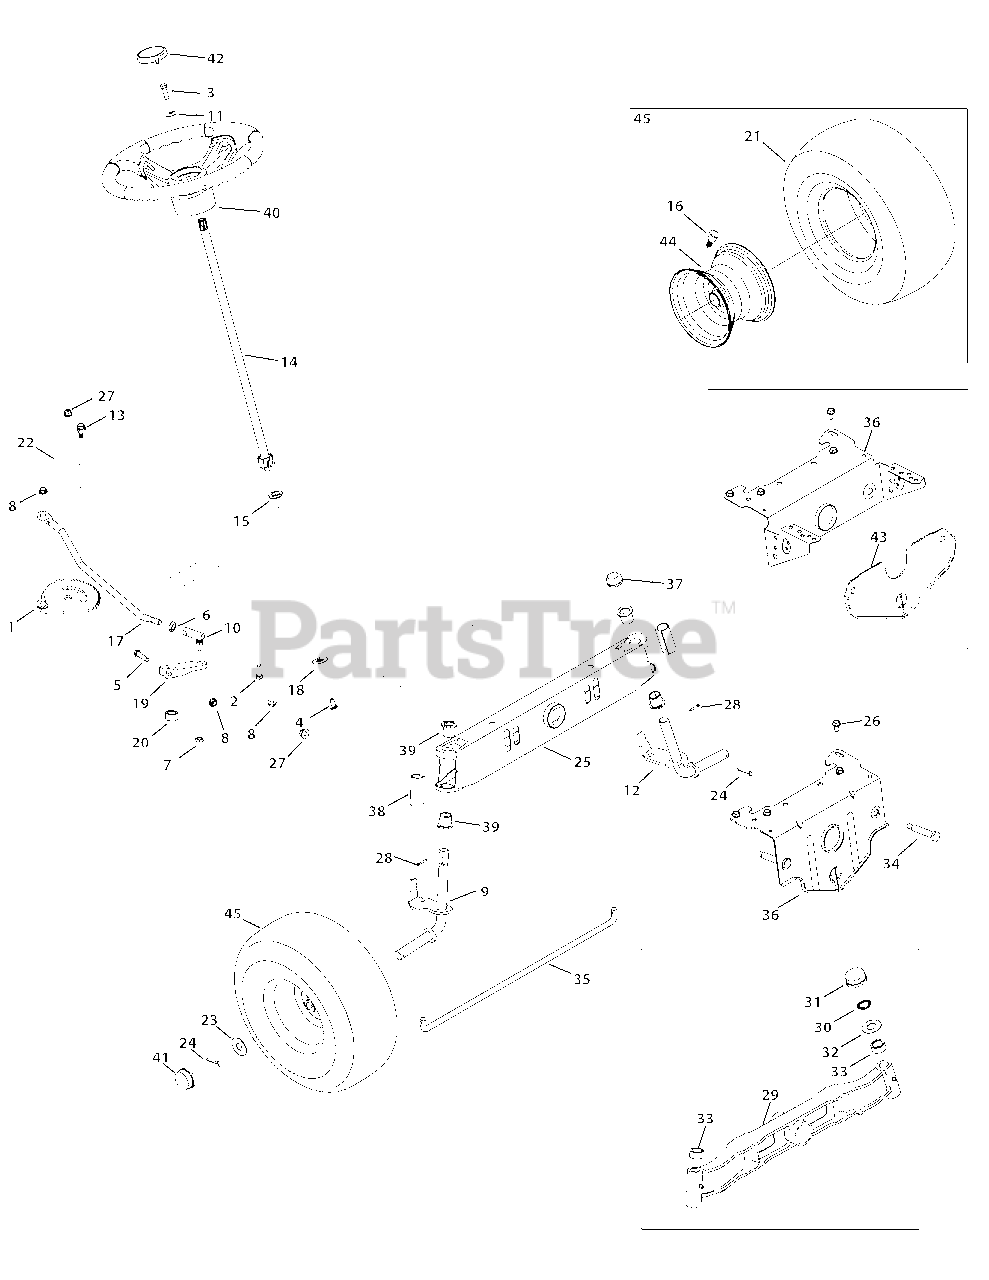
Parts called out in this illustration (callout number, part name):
1	Front Steering Gear Assembly
2	Hex Screw, 3/8-16 x 1.00
3	Hex Screw, 5/16-18 x 1.00, Lock
4	Machine Screw, 5/16-18 x .750
5	Hex Screw, 5/16-18 x 1.75
6	Jam Nut, 7/16-20
7	Jamlock Nut, 3/8-24
8	Flangelock Nut, 5/16-18
9	Axle, 42" & 46" Front RH
10	Ball Joint, 7/16-20
11	Bell Washerer, .340 x .872 x .060
12	Axle, 42" & 46" Front LH
13	Shoulder Bolt, 5/16-18 x .435 x .350
14	Steering Shaft, 5/8 x 22.08
15	Flange Bearing, 5/8
16	Valve, tubeless Air
17	Steering Link
18	Cap, 1.25 x .16
19	Steering Block
20	Spacer, .71 x .125 x .56
21	Tire, 15 X 6 X 6 Sq Shoulder
22	Shoulder Spacer, .884 x .190
23	Flat Washer, .781 x 1.590
24	Cotter Pin, 5/32 x 1.25
25	Pivot Axle
26	Screw, 5/16-18 x .750
27	Flangelock Nut, 3/8-16
28	Cotter Pin, .125 x .75
29	Pivot Axle, Cast Iron
30	Push Nut, 3/4
32	Flat Washer, .78 x 1.59 x .060
33	Spacer, 71 x 125 x 56
34	Shoulder Bolt, 3/8-16 x .500 x 2.38
36	Pivot Bar Bracket
37	Push Cap, 3/4
38	Standard Axle Cap
39	Flange Bearing, .760 x .941 x 1.0
40	Steering Wheel Soft Grip
42	Cap, Troy-Bilt
44	Rim, 6.0x4.5
45	Wheel Assembly
